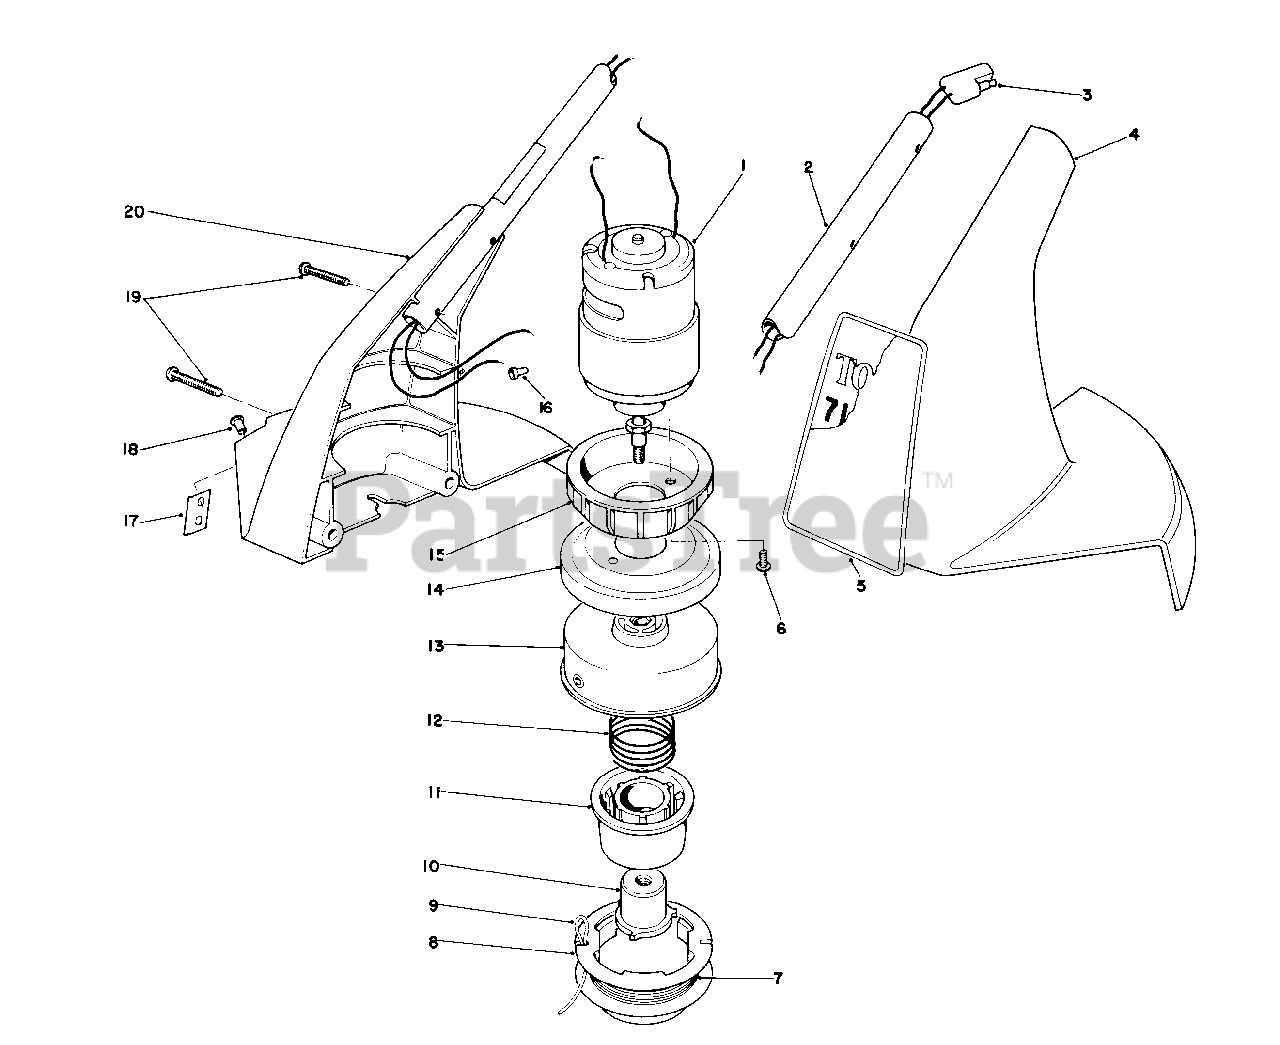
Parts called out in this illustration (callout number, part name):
2	Extension-Handle
3	Wiring Harness-Lower
4	Housing-Motor L.H.
5	Decal-Cordless
7	Line-Cutting 12' .050 " Dia. Prewound Spool
8	Spool-Empty
9	Line-Cutting 30' .050" Dia. in Coil
12	Spring
13	Drum w/Eyelet
14	Cup-Drum
15	Casting-Heat Sink
16	Connector-Wire
20	Housing-Motor R.H.( Incl. Ref . #17 &18)
